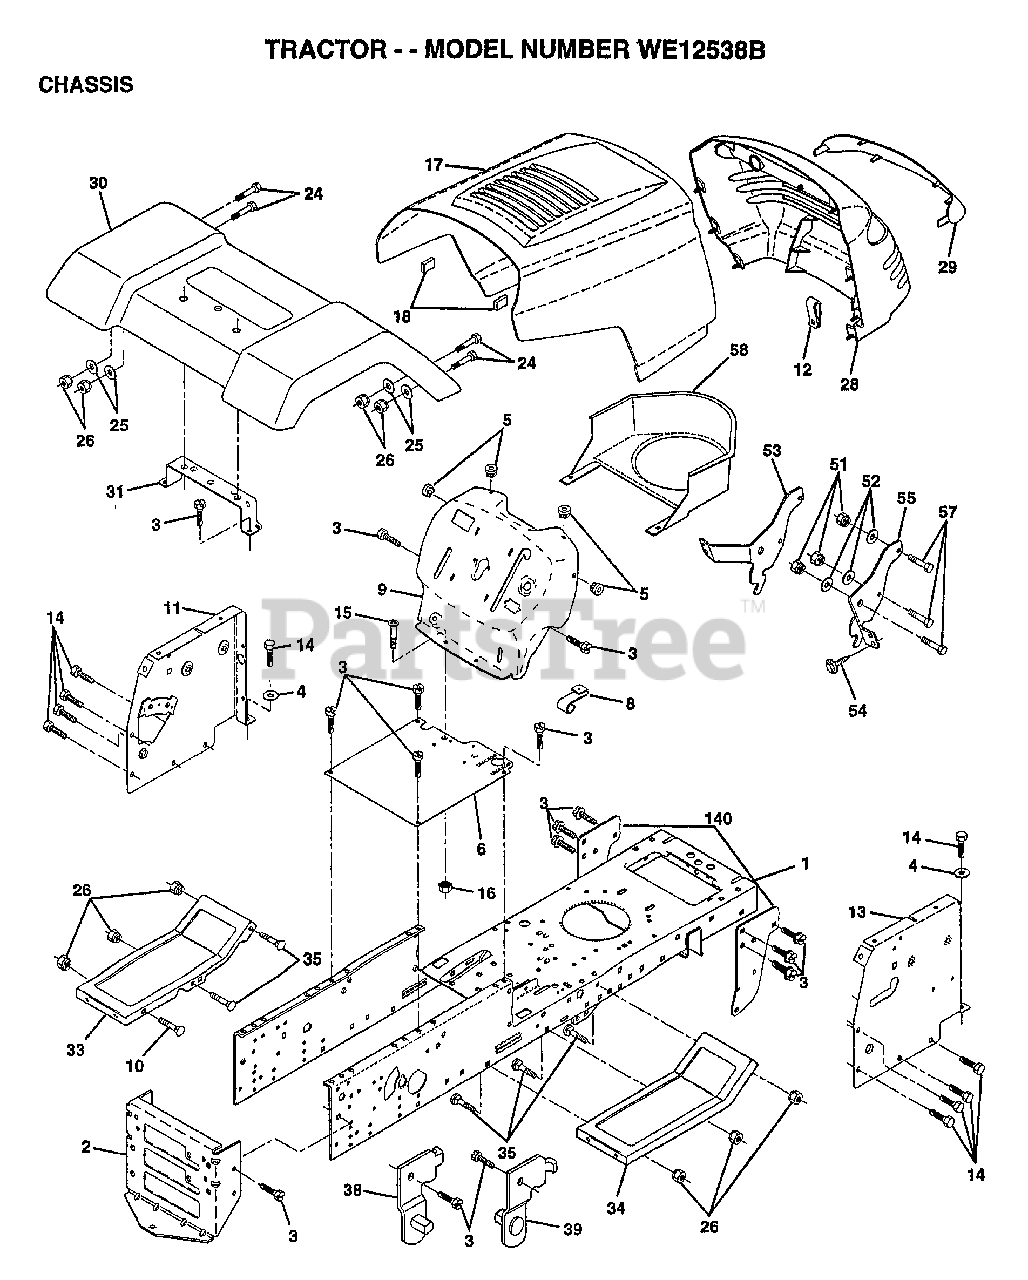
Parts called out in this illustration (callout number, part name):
1	CHASSIS ASM
3	SCREW
4	WASHER
5	BUMPER-HOOD/DASH
6	SADDLE-SILKSCREEN
8	CLIP.RETAINER
9	DASH.SILKSCREENED
11	"PANEL-DASH,LH"
12	CLIP.TINNERMAN
14	SCREW LT
15	SCREW
24	BOLT
25	WASHER
26	NUT
28	GRILLE-MS428
29	LENS GRILLE
31	BRKT FENDER
33	FOOTREST.LH.PERF.
34	FOOTREST.RH.PERF.
35	BOLT
38	BRACKET ASM LH
39	BRACKET ASM RH
51	NUT
52	WASHER
53	BRACKET.GRILLE.LH
55	BRACKET.GRILLE.RH
57	BOLT
58	AIR DUCT
140	BRKT SUSPENSION
